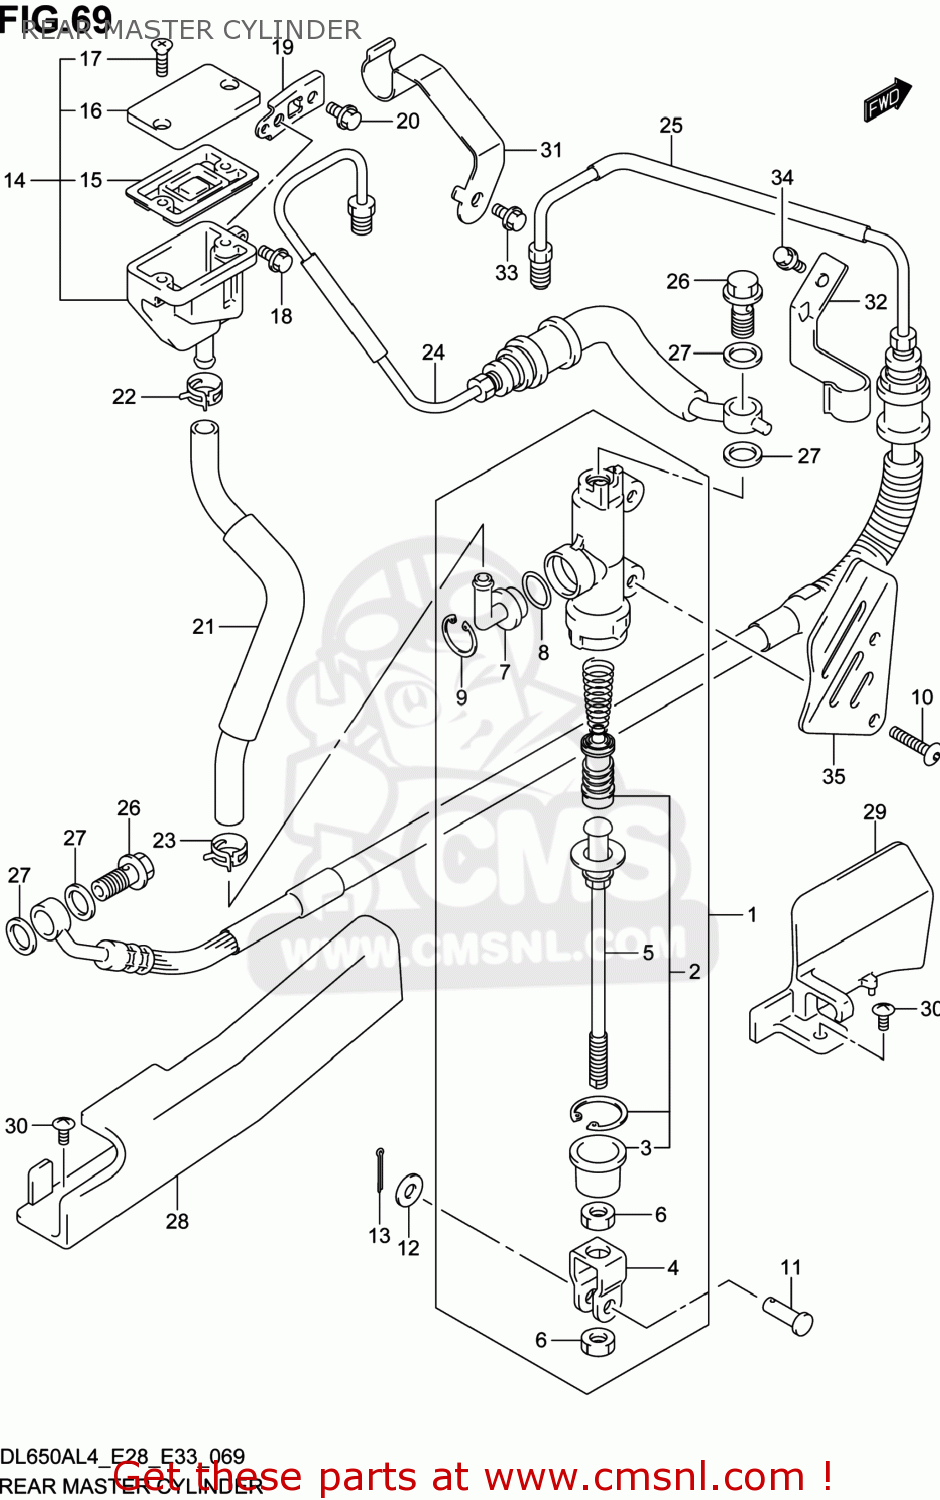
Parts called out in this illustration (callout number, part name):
1	CYLINDER ASSY,RR MASTER
2	PISTON/CUP SET
3	BOOT
4	YOKE
5	ROD,PUSH
6	NUT
7	CONNECTOR
8	O RING
9	CIRCLIP
10	SCREW(6X25)
11	PIN(6X18.2)
12	WASHER
13	PIN
14	TANK ASSY,RR RESERVOIR
15	DIAPHRAGM
16	CAP
17	SCREW
18	BOLT
19	BRACKET,RR RESERVOIR TANK
20	BOLT
21	HOSE,RR RESERVOIR TANK
22	CLIP
23	CLIP
24	HOSE ASSY,RR BRAKE NO.1
25	HOSE ASSY,RR BRAKE NO.2
26	BOLT UNION
27	WASHER(10X15X1.5)
28	GUIDE,RR BRAKE HOSE
29	GUIDE,RR BRAKE HOSE FR
30	SCREW
31	CLAMP,RR BRAKE HOSE
32	CLAMP,RR BRAKE HOSE NO.2
33	BOLT
34	BOLT
35	COVER,RR MASTER CYLINDER
